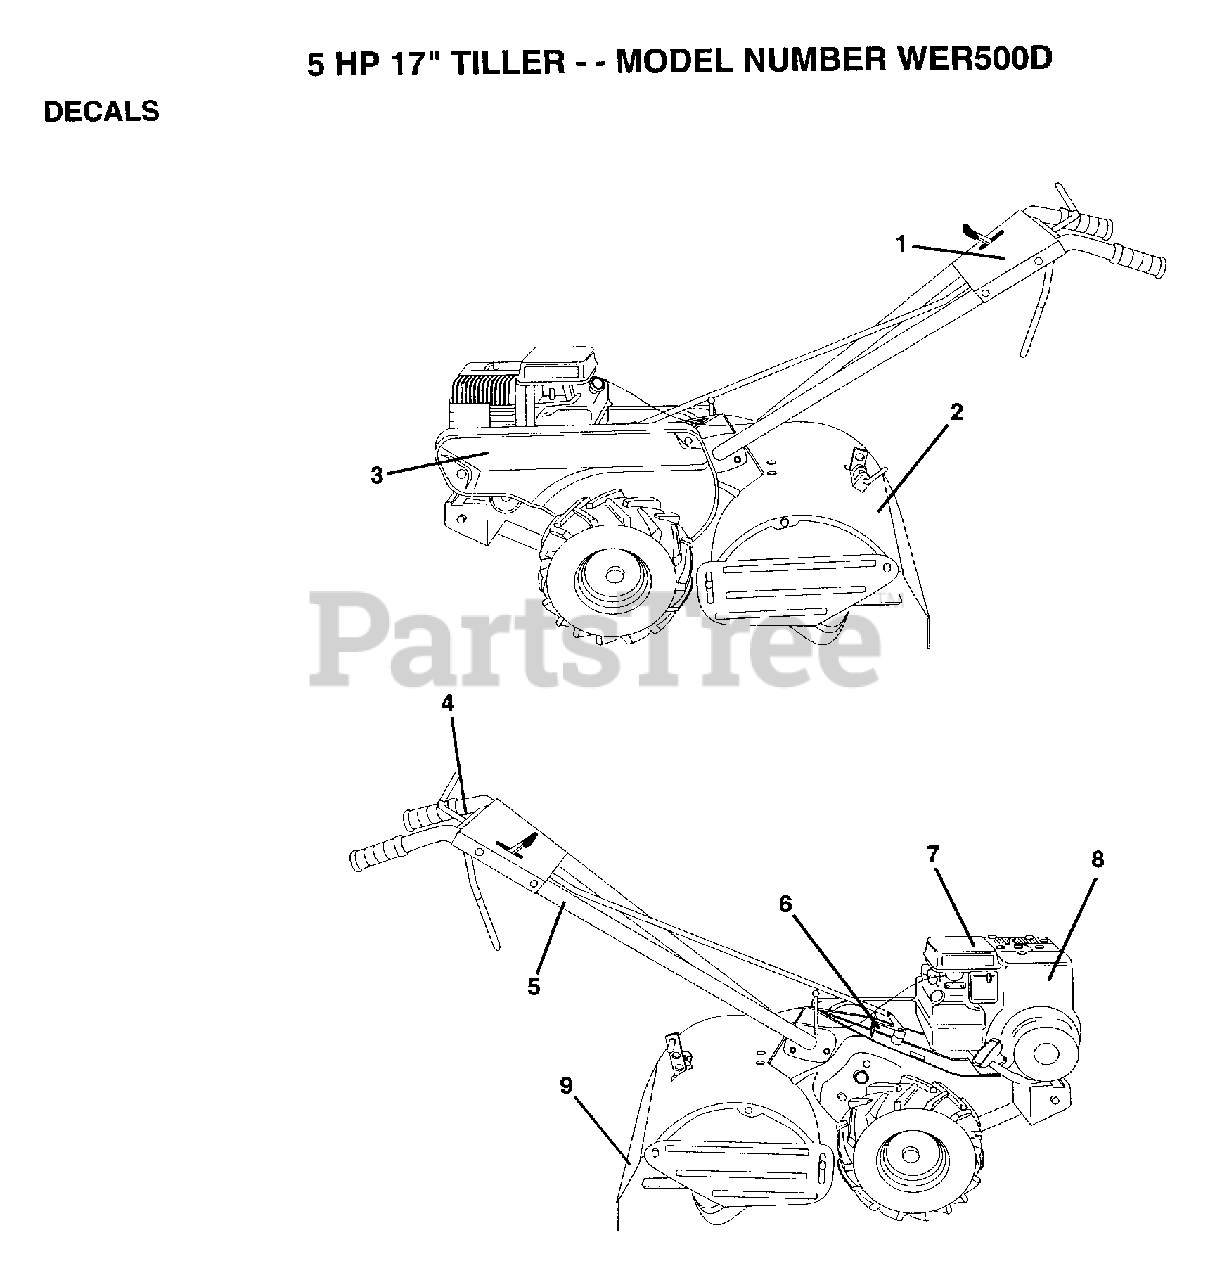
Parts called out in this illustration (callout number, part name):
1	DECAL LOGO 17 5HP
2	DECAL SHIELD TINE
3	DECAL BELT GUARD
5	DECAL TI
7	DECAL TI
